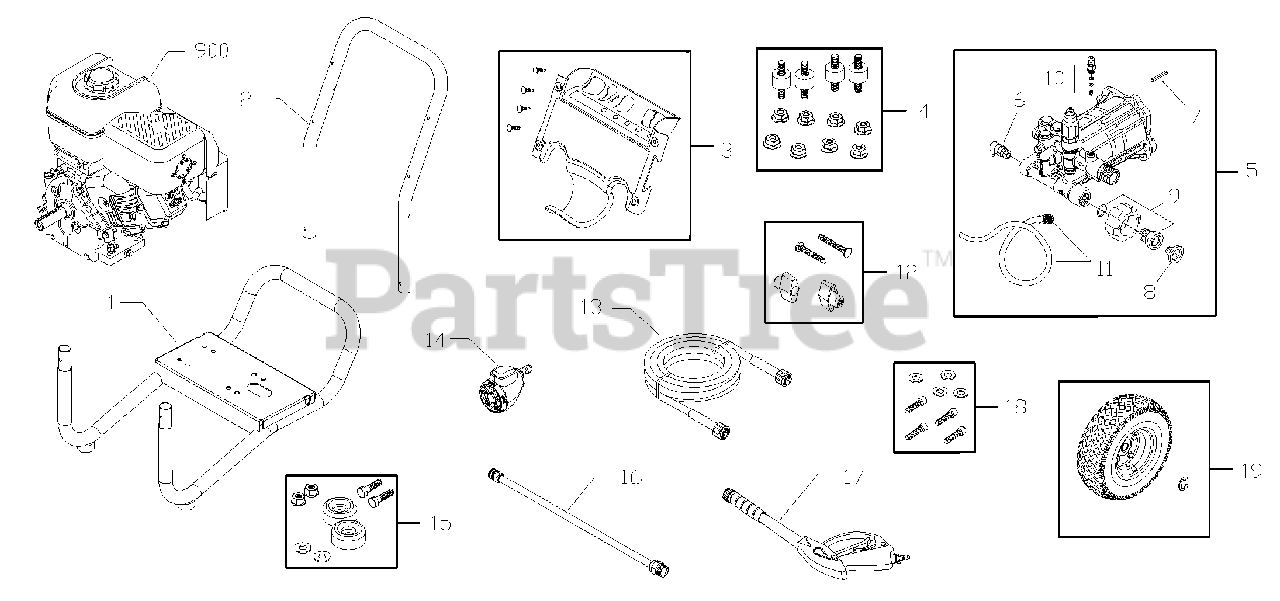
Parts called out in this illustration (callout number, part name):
2	HANDLE
4	KIT, Vibration Mount
5	PUMP
6	VALVE, Thermo Relief
8	FILTER, Garden Hose
9	KIT, Water Inlet
10	KIT, Chemical Injection
11	KIT, Chemical Hose
12	KIT, Hardware, Handle
14	NOZZLE, QC
15	MOUNT, Vibration
16	EXTENSION, QC
17	GUN
18	KIT, Hardware, Pump Mounting
